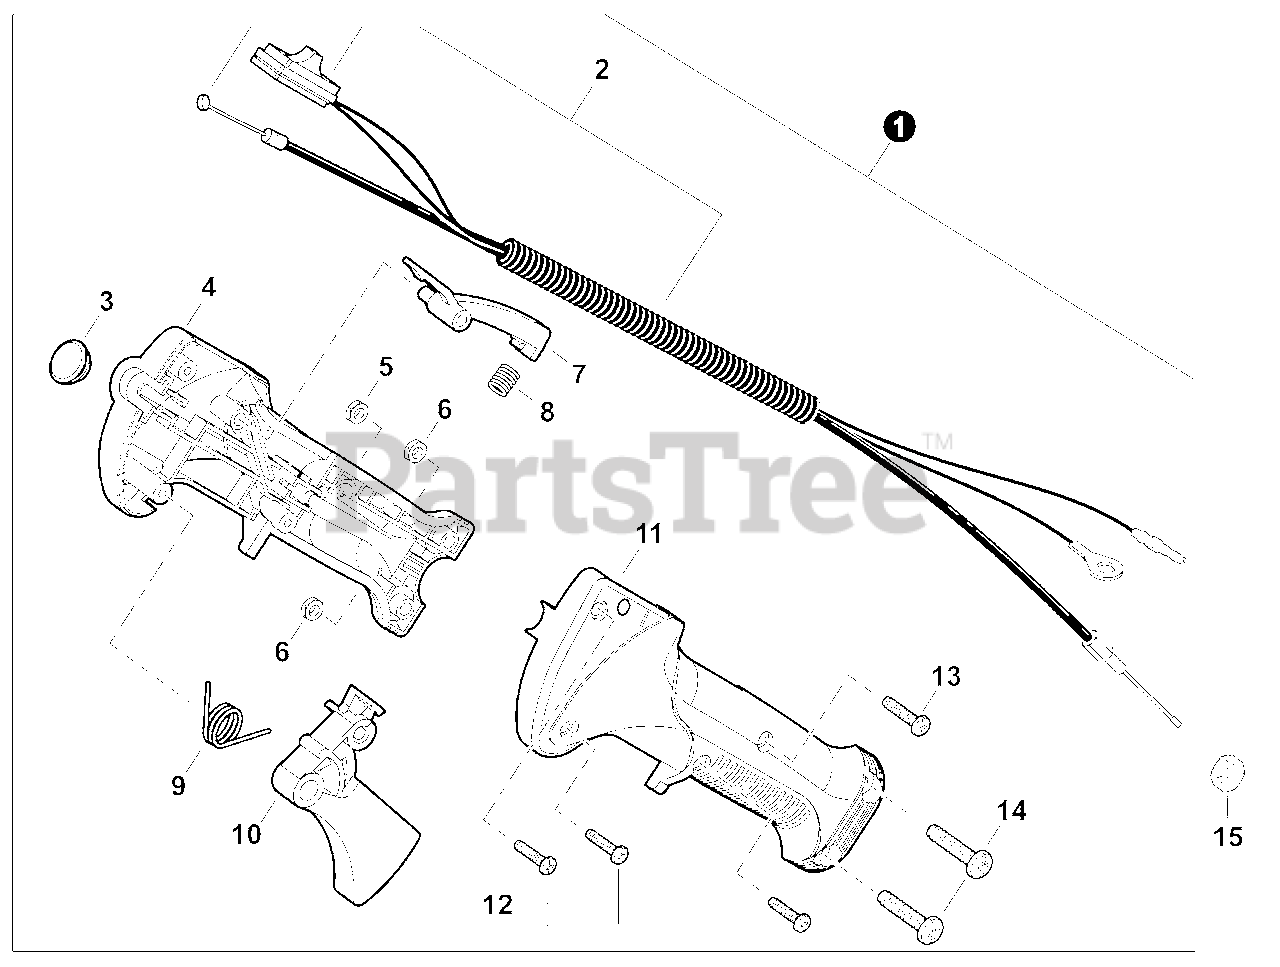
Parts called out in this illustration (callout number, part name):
1	THROTTLE CONTROL ASSY
2	CABLE ASSY, CONTROL
3	PLUG, RUBBER
4	CONTROL HANDLE - RIGHT
7	LOCKOUT, THROTTLE
8	SPRING, COMPRESSION
9	SPRING, TORSION
10	TRIGGER, THROTTLE
11	CONTROL HANDLE - LEFT
12	SCREW, TAPPING 4×16
13	SCREW M4×23
14	SCREW M5×22
